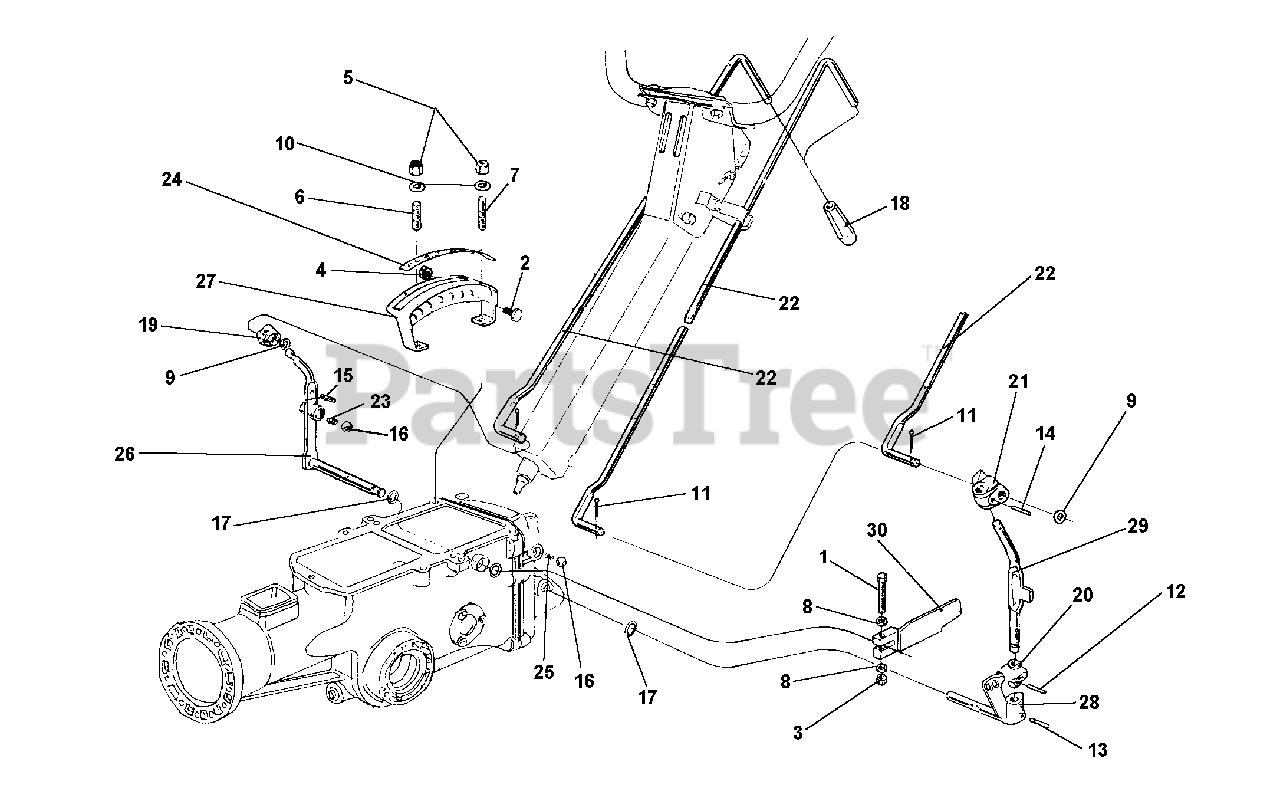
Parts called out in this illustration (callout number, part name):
1	SCREW M6 X 40
2	SCREW M8 X 14
3	NUT, SELF LOCKING M6
4	NUT, SELF LOCKING M8
6	STUD M8 X 38 X 14 X 20
7	STUD M8 X 46 X 16 X 16
8	FLAT WASHER 6.4
9	WASHER P10.5 X 18
10	SUPER WASHER 8 DIN 6796
12	LOCKING PIN 4 X 20 SPIRAL
14	LOCKING PIN 4 X 24 SPIRAL
15	LOCKING PIN SPIRAL
16	BALL 15/32 RIV RB-11.906
17	O-RING 115 11.91 X 2.62
19	JOINT, 715, 725, 735
20	PTO STOP RING
21	PTO ARTICULATION
22	ROD, CONTROL, POWER TILLER
24	SPEED DECAL, 725, 735, 745
26	GEARBOX LEVER
27	SPEED QUADRANT, 725, 735, 745
28	PTO CONTROL PIN, 715, 725, 735
29	PTO CONTROL LEVER
30	PTO LOCKOUT, 725, 735
